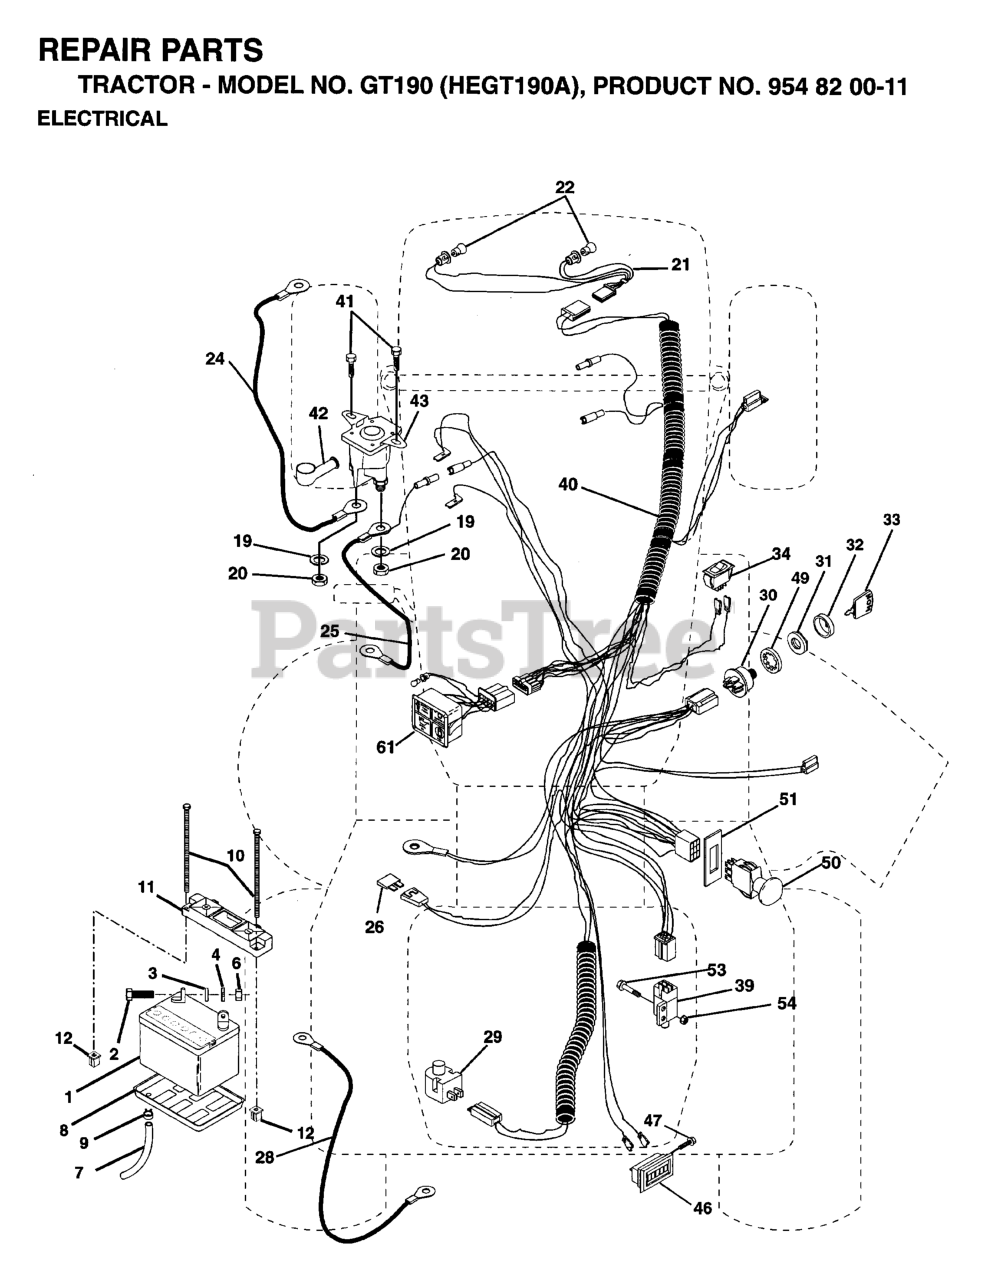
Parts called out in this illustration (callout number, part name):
1	BATTERY 12 VOLT 30 AMP WET
2	BOLT.HEX.1/4.X.3/4.DICHROMATE
3	LOCKWASHER
6	NUT
7	PLASTIC TUBE
8	BATTERY TRAY T
9	HOSE CLAMP T
10	BOLT 1/4-20 X 7.5
11	HOLDDOWN, BATTERY, DASH MOUNT
12	NUT, PUSH NYLON 1/4" BATTERY
19	LOCKWASHER
20	NUT
21	HARNESS LIGHT SOCKET
24	BATTERY CABLE GT
25	CABLE, BATTERY
28	CABLE T
29	RP.SWITCH.PLUNGER.NC.GRAY
30	IGNITION SWITCH
31	NUT, IGNITION
32	COVER SWITCH KEY
33	KEY MLD GEN DELTA
39	SWITCH INTERLOCKT
41	SCREW
42	TERMINAL COVER
43	SOLINOID
46	HOUR METER T
47	Screw 10-24 x 1/2 Black
49	Washer, Lock Internal Tooth 5/8
50	SWITCH-PTO
51	FRAME RETAINING RING
53	SCREW **
54	Nut, Hex, Keps #10-32 UNF
61	LIGHT PACKAGE
62	BULB LIGHT T
